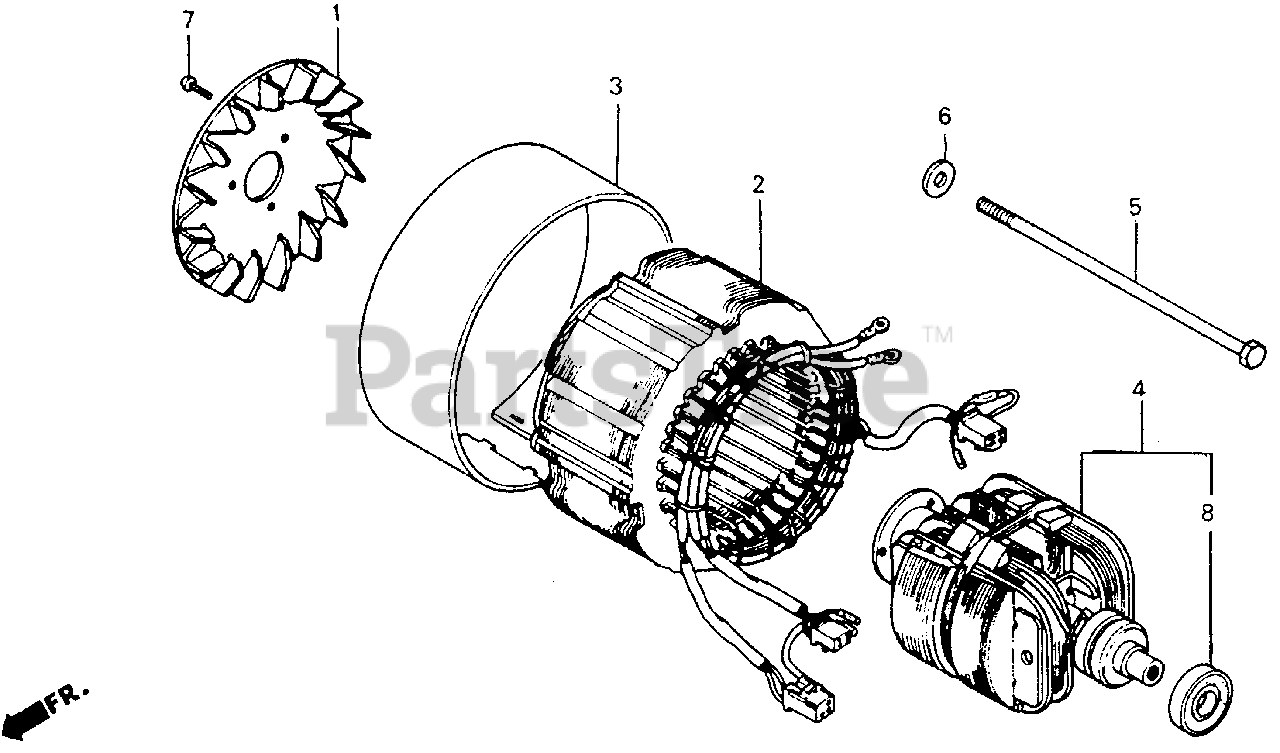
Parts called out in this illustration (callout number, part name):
2	STATOR ASSY. (NOT AVAILABLE)
3	COVER, STATOR *R8* (BRIGHT RED)
4	ROTOR
5	BOLT, HEX. (10X235)
6	WASHER, PLAIN (10MM)
7	SCREW, TAPPING (5X14)
7	SCREW, PAN (5X10)
8	BEARING, RADIAL BALL (6304UU)
